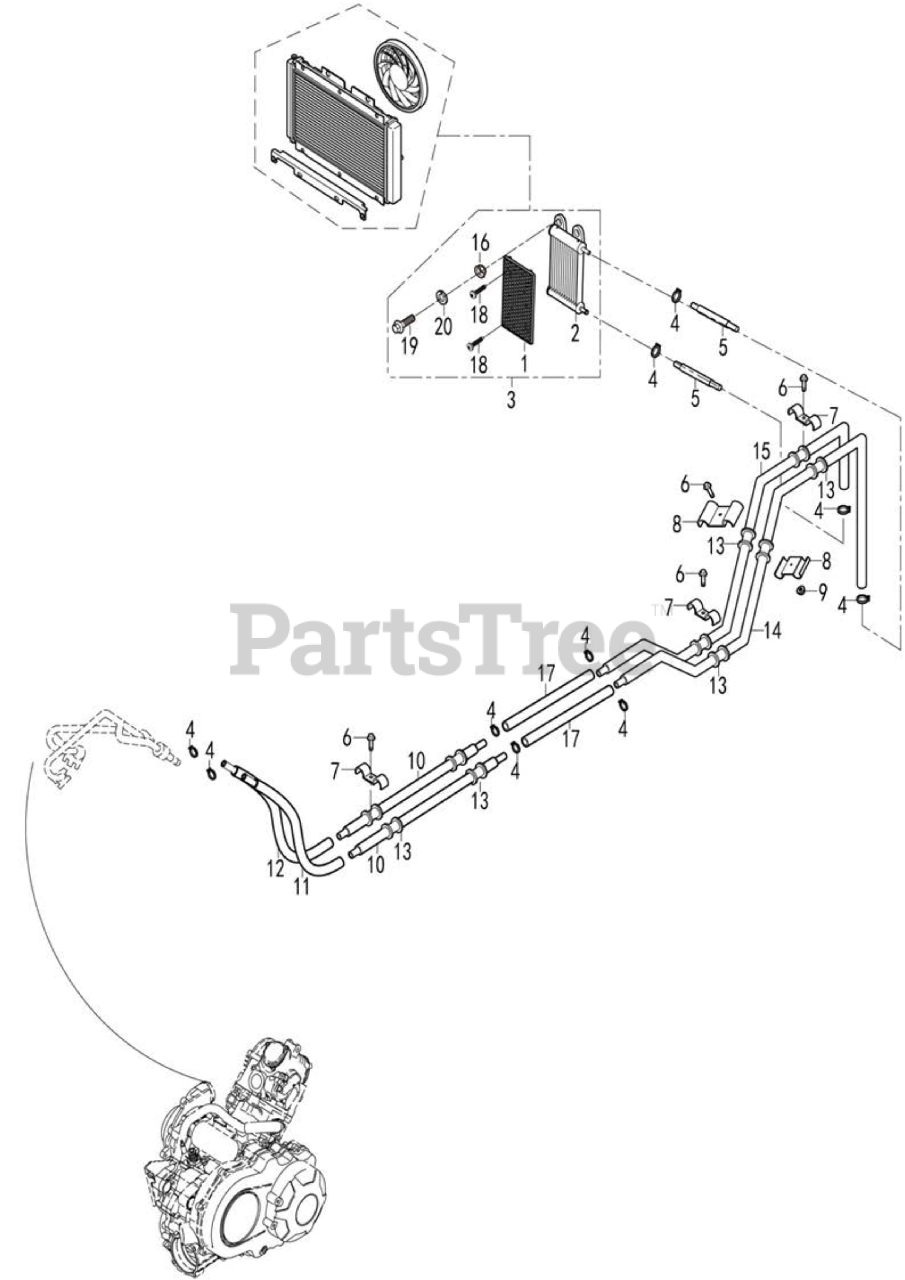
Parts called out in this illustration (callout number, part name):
1	Oil Cooler Cover
2	Weding Oil Cooler Assy
3	lubricating oil cooler
4	Locking Hoop For Screw A
5	rubber fuel line
6	Cross Large Plate Head Screw M6X12
7	fixing pipe clamp(M type)
8	fixing pipe clamp(M type)
9	Hexagon Flange Nut M6
10	Metal Oil Pipe ?
11	Pressureproof Rubber Oil Pipe?
12	Pressureproof Rubber Oil PipeII
13	fuel line rubber
14	Metal Oil PipeII
15	Metal Oil PipeI
16	Flange Nut M6
17	pressureproof Rubber Pipeline I
18	Cross Small Plate Head Screw ST3.5X18
19	Hexagon Flange Bolt M6X14
20	Spring washer 6
